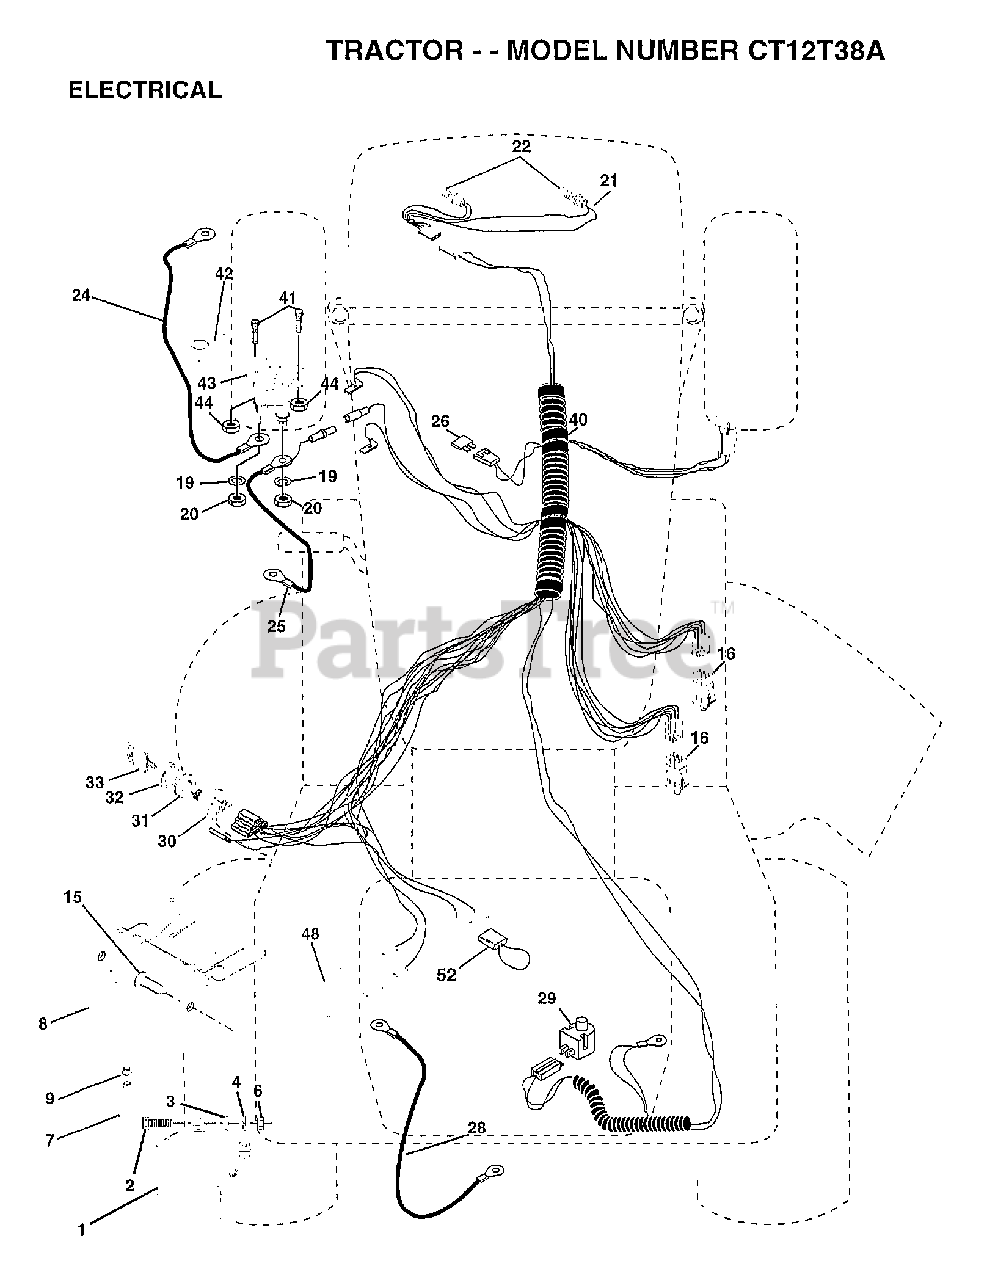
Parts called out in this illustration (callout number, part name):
2	BOLT LT
3	WASHER
4	LOCKWASHER
7	TUBE T
8	"CASE,BATTERY.MECH"
9	HOSE CLAMP T
15	FASTNER.SNAP-IN
16	SWITCH INTERLOCK
20	NUT
21	"HARNESS,LIGHT SOC"
22	HEADLAMP BULB
24	CABLE ASM.
25	CABLE.BTRY.6GA.RD
26	FUSE HYT
28	CABLE T
29	SWITCH SEAT
30	SWITCH IGN 4POS
31	NUT IGNITION
32	COVER KEY SWITCH
33	KEY
40	HARNESS-IGNITION
41	BOLT HXHD FIN
44	NUT HXKEP 1/4X20
48	ADAPTER AMMETER
52	PROTECTION LOOP
